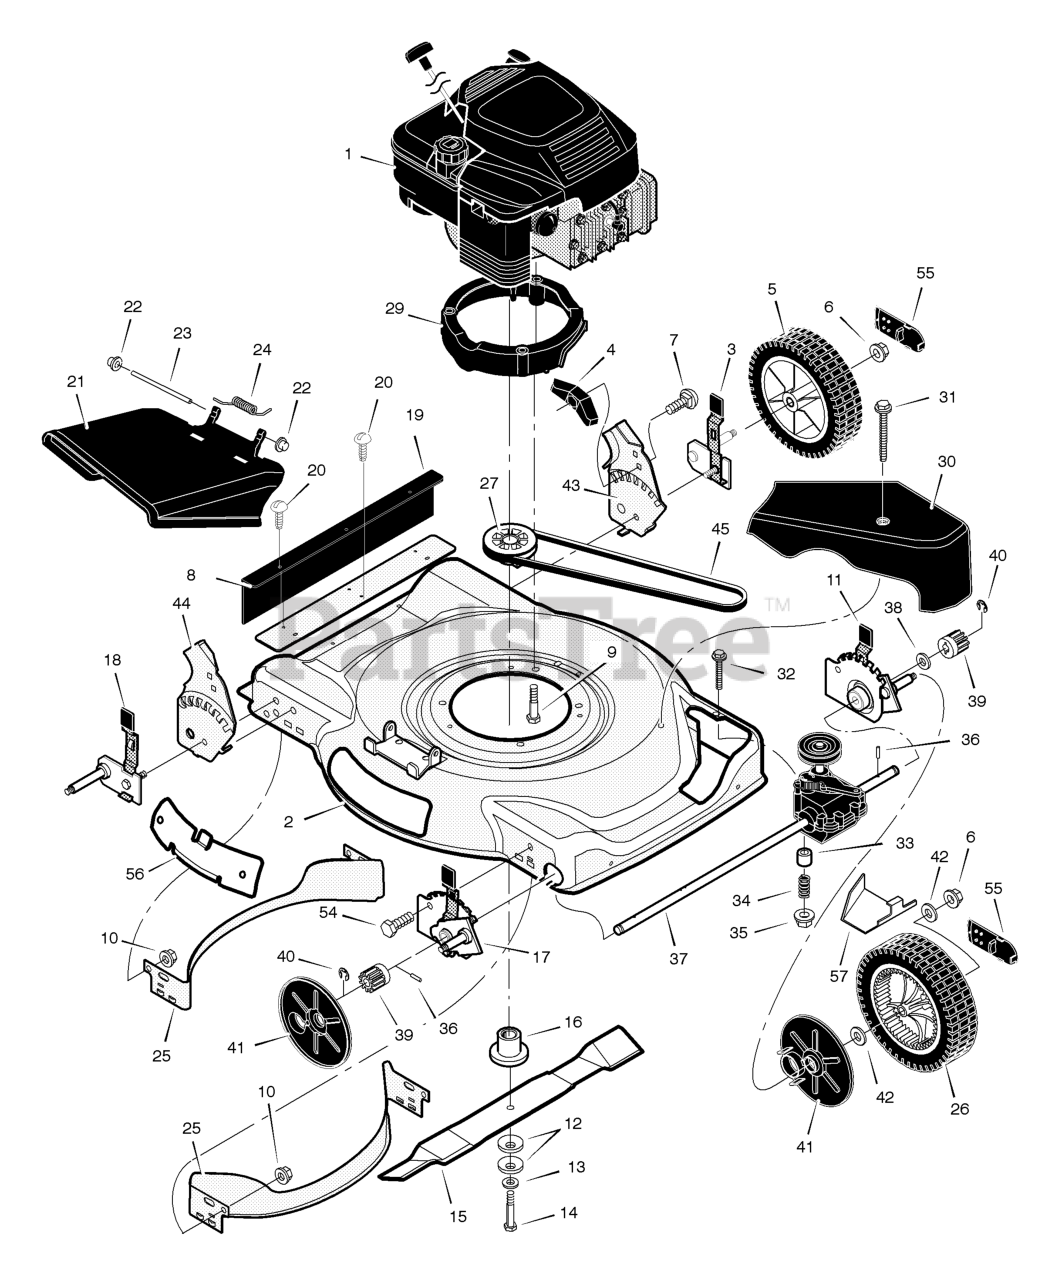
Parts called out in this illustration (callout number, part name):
1	Engine *
2	Housing
3	Height Adjuster, Left Rear
5	Wheel and Tire, Rear
6	Locknut, Flange
7	Bolt, Carriage
8	Extension, Rear
9	Bolt, Engine
10	Nut
11	Height Adjuster, Left Front
12	Washer, Belleville
14	Bolt, Hex
16	Adapter, Blade
17	Height, Adjuster, Right Frt.
18	Height, Adjuster, Right Rr.
19	Guard, Rear
21	Deflector, Chute
22	Push-On Cap
23	Pin, Pivot
25	Baffle
26	Wheel and Tire, Drive
29	Base, Engine
30	Cover, Belt (Black)
35	Nut
36	Pin, Drive
37	Transmission *
39	Gear, Pinion
41	Cover, Dust
42	Washer
43	Bracket, Left Handle
44	Bracket, Right Handle
45	Belt, Briggs & Stratton
54	Bolt
55	Hub Cap
56	Plate, Mulch
57	Cover, Transmission
